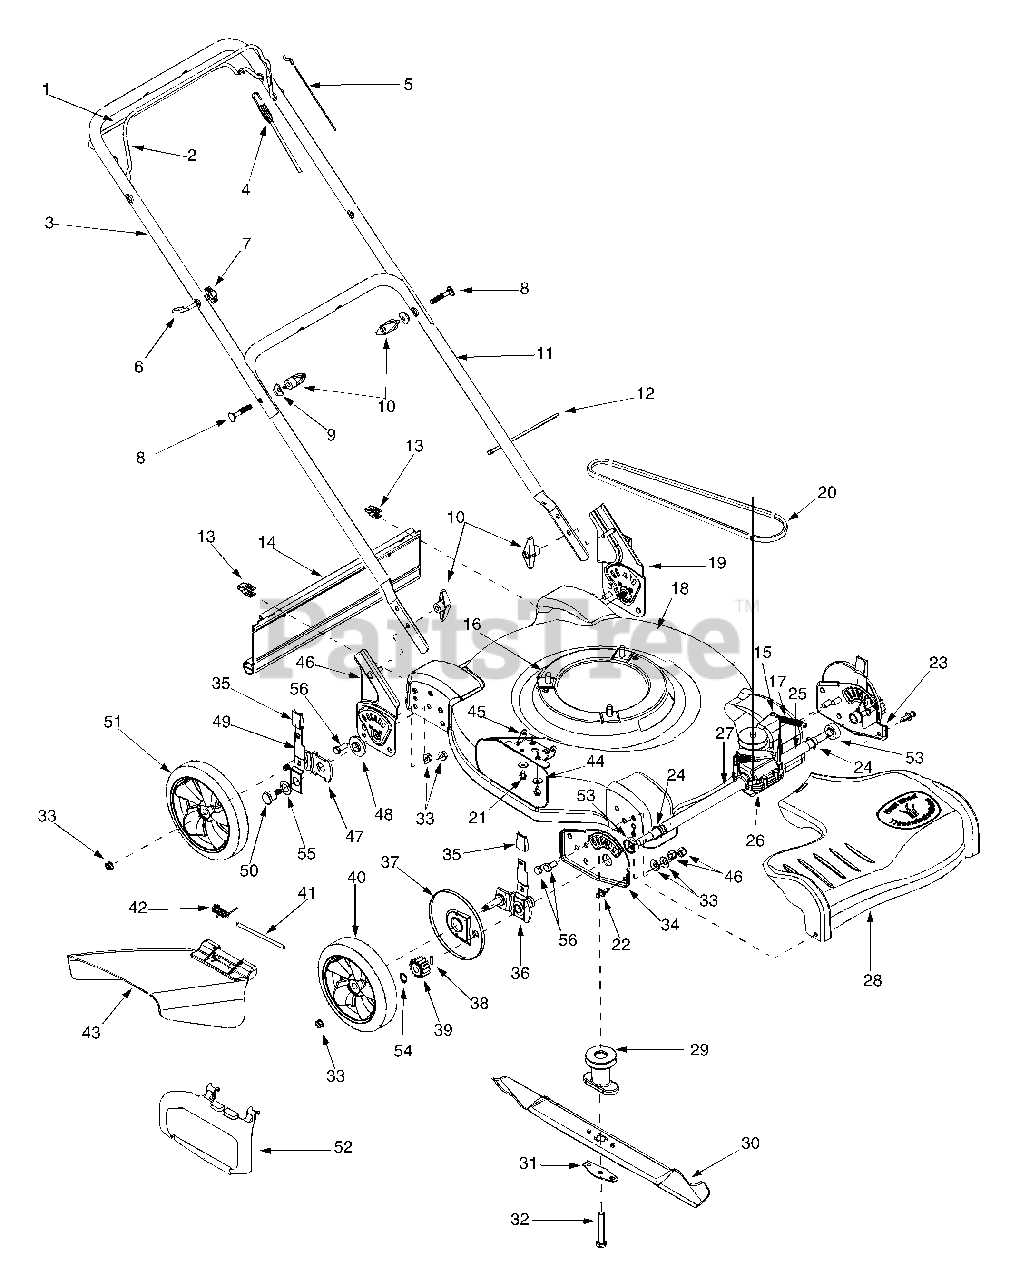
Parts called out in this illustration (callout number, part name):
1	Drive Control Handle
4	Drive Control Cable
5	Blade Control Cable - 40.75"
5	Blade Control Cable - 50.56"
6	Eye Bolt
7	Wing Nut 1/4-20
8	Carriage Bolt 5/16-18 x 2.0
9	Shoulder Washer.320 ID x.93 OD
10	Wing Nut 5/16-18
12	Cable Tie
13	Hinge Clip
14	Trail Shield
15	Screw (Included with Item No. 28)
16	Hex Washer Screw 3/8-16 x 1.0
17	Spring.47 OD x 2.50
20	V-Belt
21	Hex Washer Screw 1/4-20 x.500
22	Rivet
24	Retainer Ring
25	Sleeve Spacer.550 ID X 2.22
26	Transmission Assembly Complete
27	Sleeve Spacer.550 ID x7.42
28	Transmission Cover
29	Blade Adapter, One Piece
30	Mulching Blade 22"
31	Bell Blade Support
32	Hex Cap Screw 3/8-24 x 1.5
33	Lock Nut 3/8-16
35	Adjustment Knob
36	Spring Lever Assembly - LH Not Pictured
36	Spring Lever Assembly - RH Pictured
37	Wheel Dust Cover
38	Pin
39	Spur Gear 14T - RH
39	Spur Gear 14T - LH
40	Front Wheel Assembly 8 x 1.8
41	Hinge Pin
42	Torsion Spring
43	Side Discharge Assembly
44	Bell Washer.265 ID x.75 OD
45	Deflector Chute Adapter
48	Height Adjustment Bearing
49	Spring Lever
50	Shoulder Screw 3/8-16
51	Rear Wheel 8 x 1.8
52	Snap Mulching Plug
53	Bearing Spacer
54	Snap Ring.500
55	Bell Washer.760 ID x 1.25 OD
56	Hex Cap Screw 3/8-16 x .75
